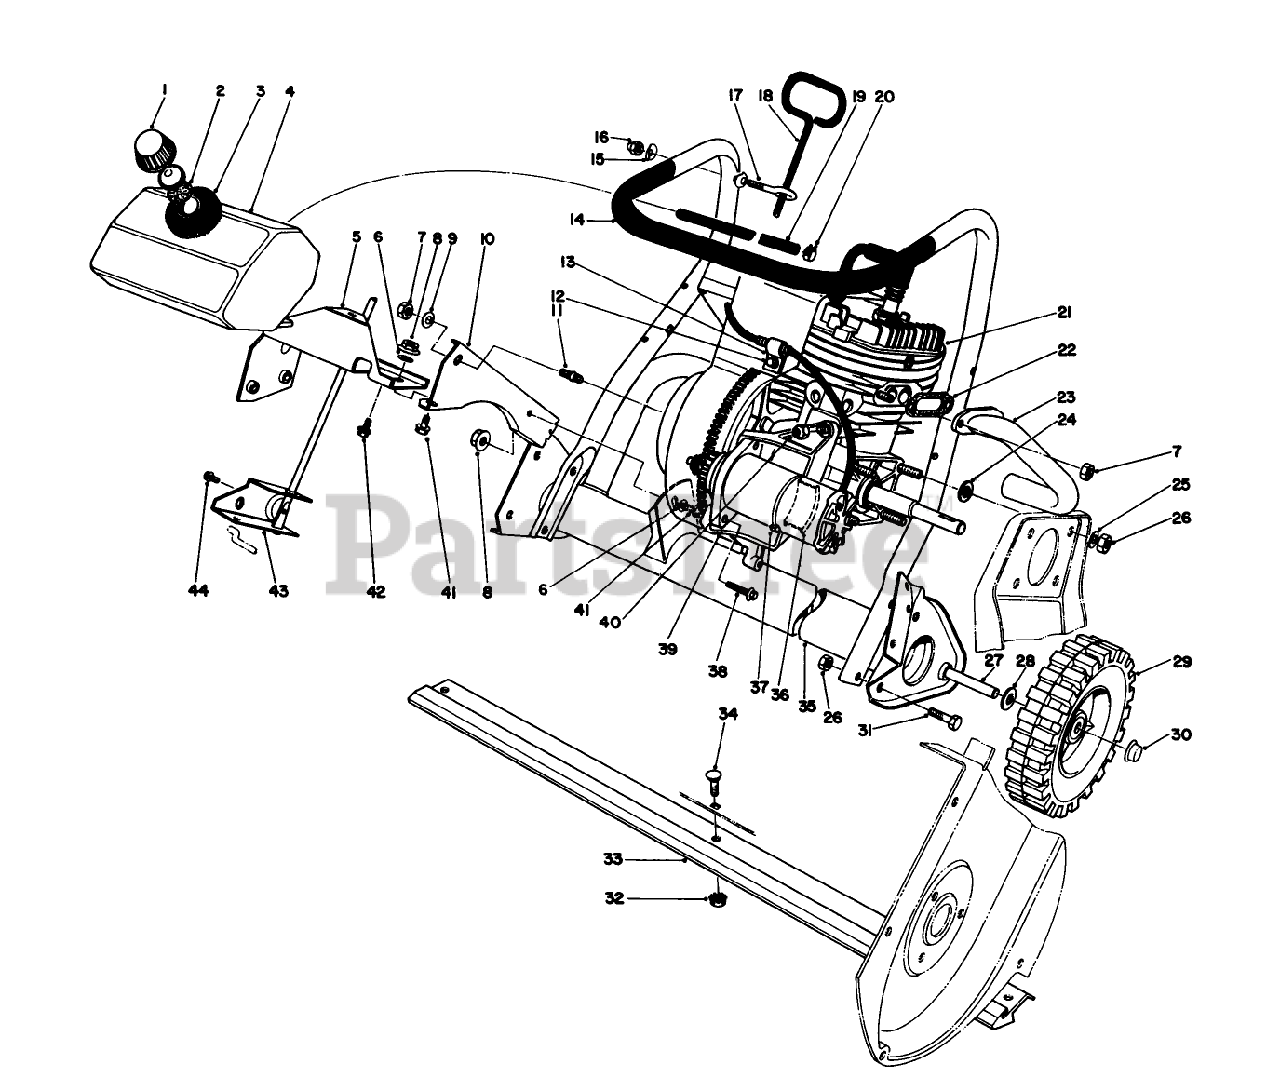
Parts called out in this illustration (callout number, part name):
1	GAS CAP ASM 32:1
2	GAS CAP GASKET
6	WASHER-LOCK
7	NUT-LOCK, CONE
10	ENGINE SUPPORT
12	SCREW-HWH
15	WASHER
16	NUT-CAP
17	EYEBOLT
18	ADJ ROD ASM
21	Engine
24	WASHER-FLAT
25	WASHER-PLAIN
26	NUT-LOCK, NI
28	WASHER-FLAT
29	WHEEL
30	NUT-PUSH
31	SCREW-HH
32	NUT-KEPS
33	SCRAPER
34	BUTTON HD CARR SCR
35	MUFFLER ASSEMBLY
37	TIE-CABLE
38	SCREW-FLOW, TAPTITE
40	NUT-LOCK, NI
42	SCREW-HWH
44	SCREW
